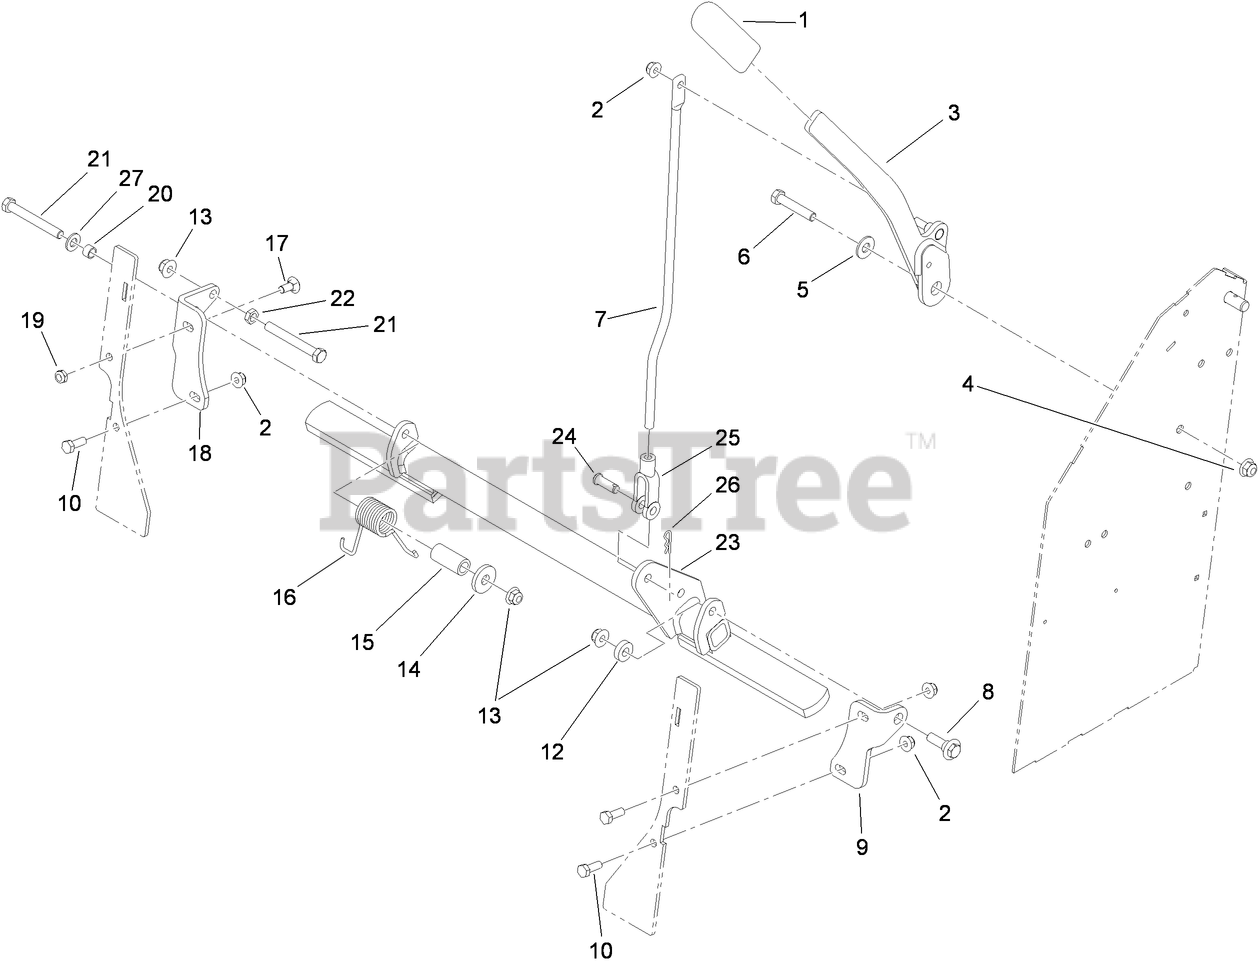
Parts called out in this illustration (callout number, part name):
1	GRIP-LEVER
2	NUT-HF, NI
3	HANDLE-BRAKE
4	NUT-HF, NI
5	WASHER-FLAT
6	SCREW-HH
7	ROD-LINK, BRAKE
8	SCREW-SHOULDER, HWH
9	BRACKET-BRAKE MOUNT, LH
10	SCREW-HH
12	SPACER
13	NUT-HF, NI
14	WASHER
15	SPACER
16	SPRING-TORSION
17	BOLT-CARR
18	BRACKET-BRAKE MOUNT, RH
19	NUT-LOCK, NI
20	SPACER
21	SCREW-HH
22	NUT-JAM
23	BRAKE ASM
24	PIN-CLEVIS
25	YOKE-LINKAGE, BRAKE
26	PIN-COTTER
27	WASHER-FLAT
